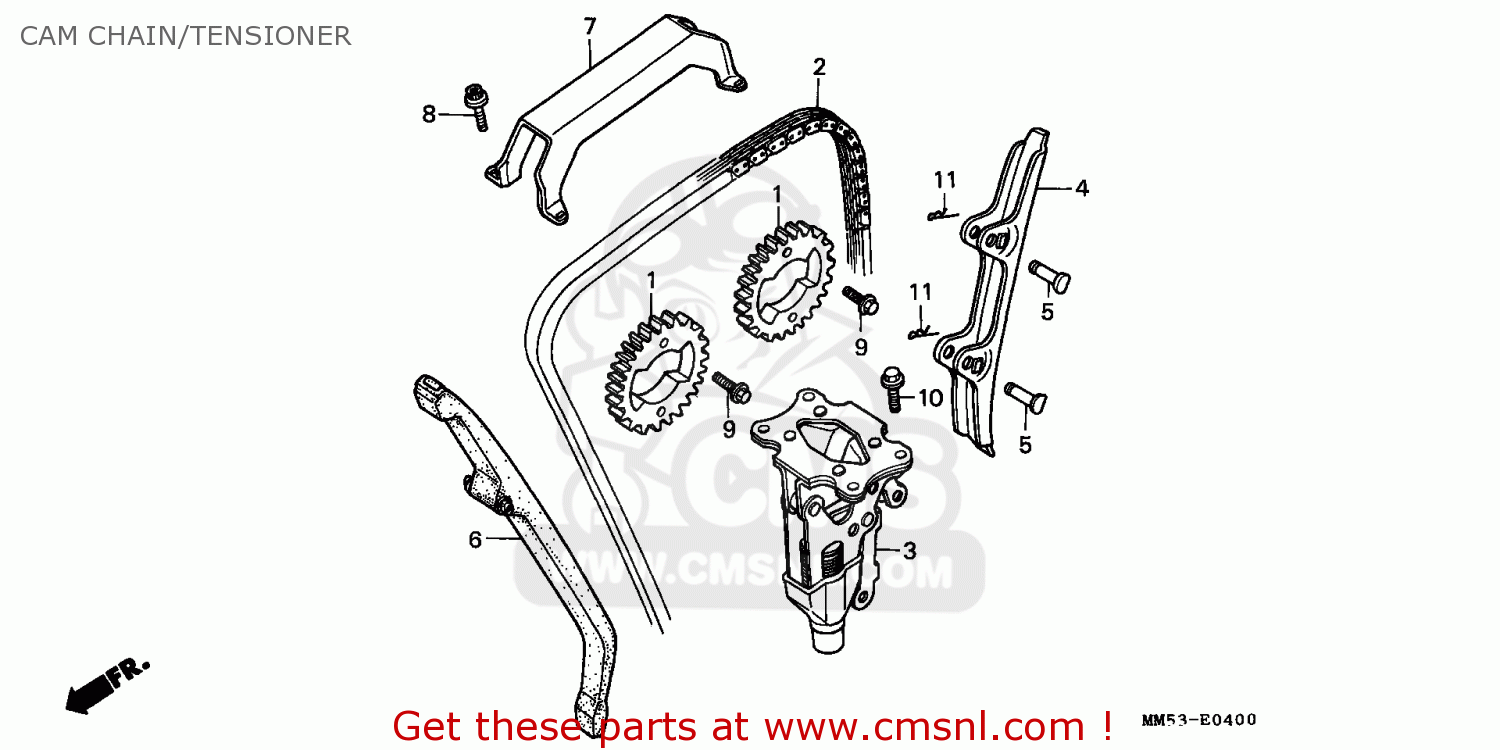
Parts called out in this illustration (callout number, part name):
1	SPROCKET,CAM (46T
2	CHAIN CAM
3	BRACKET COMP.,TEN
4	SLIPPER,CAM CHAIN
5	PIN,TENSIONER ARM
6	GUIDE A,CAM CHAIN
7	GUIDE B,CAM CHAIN
8	BOLT,SOC,FLG,6X16
9	BOLT,UBS,7X15
10	BOLT,NOCK,6MM
11	PIN,LOCK SPECAIL,
